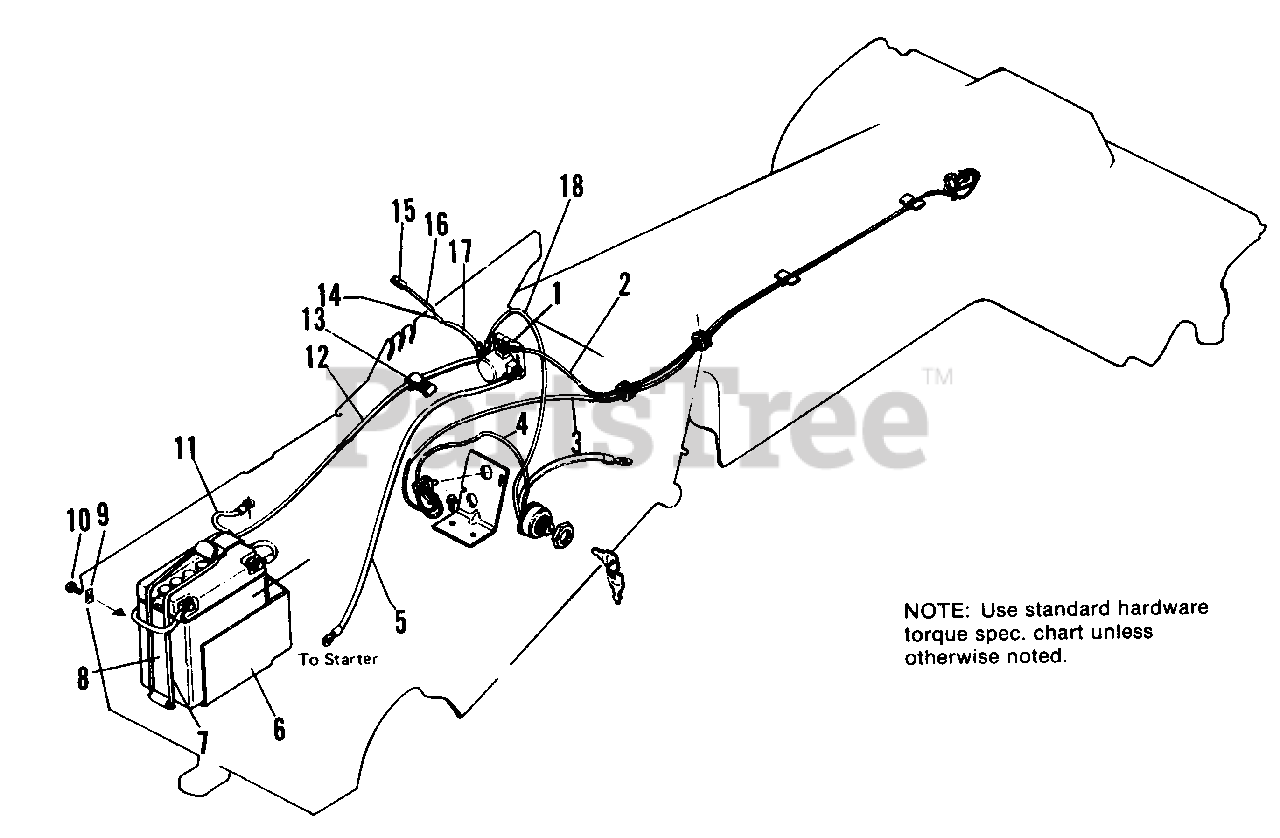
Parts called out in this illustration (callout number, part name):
2	WIRE ASSY. (PTO switch to solenoid)
4	WIRE ASSY. (Switch to ignition switch)
5	CABLE ASSY., Solenoid (To starter)
6	SUPPORT ASSY. (Battery)
7	CLIP, Wire
8	BATTERY & CLIP ASSY.
9	NUT, Speed
10	SCREW, Self Tapping, #10 x 1/2
11	CABLE ASSY. (Battery neg. to ground)
12	CABLE ASSY. (Battery to solenoid)
13	CLIP, Cable
15	FUSE, 7-1/2 Amp
16	WIRE ASSY.
17	WIRE ASSY.
18	WIRE ASSY., Ignition (Switch to Solenoid)
